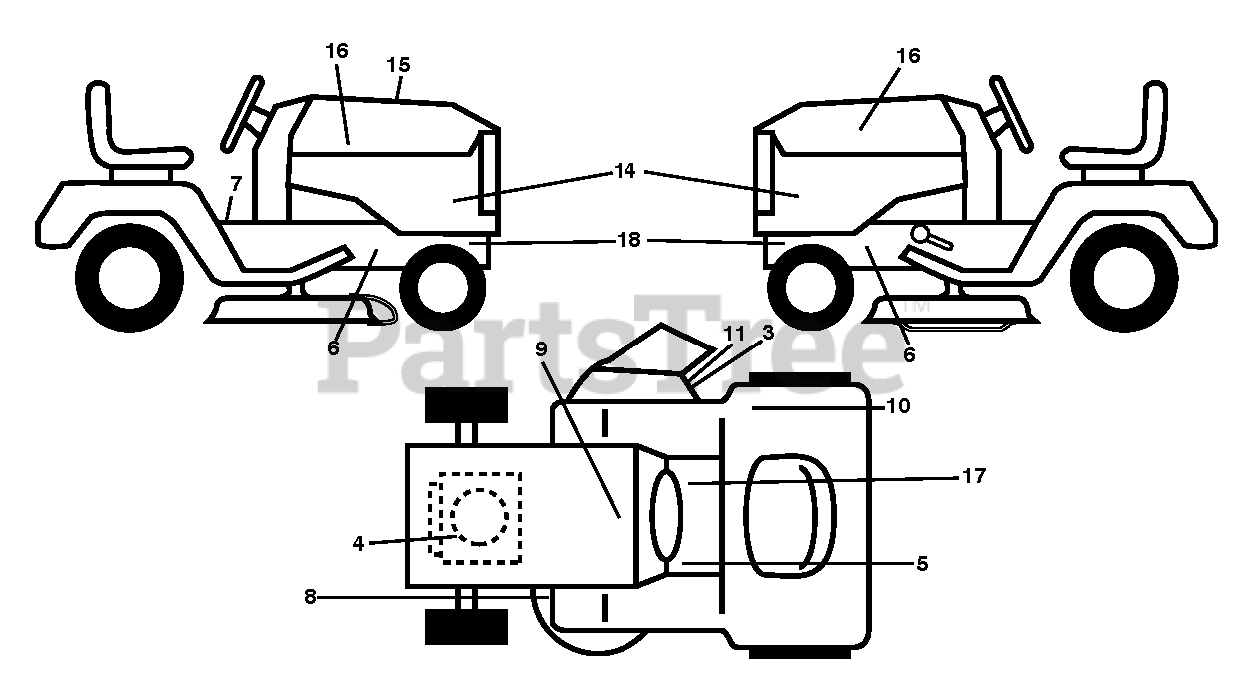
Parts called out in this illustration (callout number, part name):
1	DECAL.PEDALS.SYMBOL
3	DECAL.DFLCTR.WARNNG.CTFNGR.SYM
4	DECAL.ENGINE.WARNING
5	DECAL.FNDR.SDLE.BRAKE.CLUTCH.6
6	DECAL.WARNING.SERVCE/FIRE
7	DECAL.READ.OWN.MAN.SYMBOL.LT
8	DECAL.MOWER.SCH.48/54.PREM
9	DECAL BTRY SYMBOLS
10	DECAL.FENDER.105DB/CE.
11	DECAL.CUTFINGER.CE.02
16	DECAL.BADGE.170MM.TEXTLOGO.
17	DECAL.PARKING.BRAKE.SADDLE.LT
18	DECAL.CHASSIS.HOT.MUFFLER
